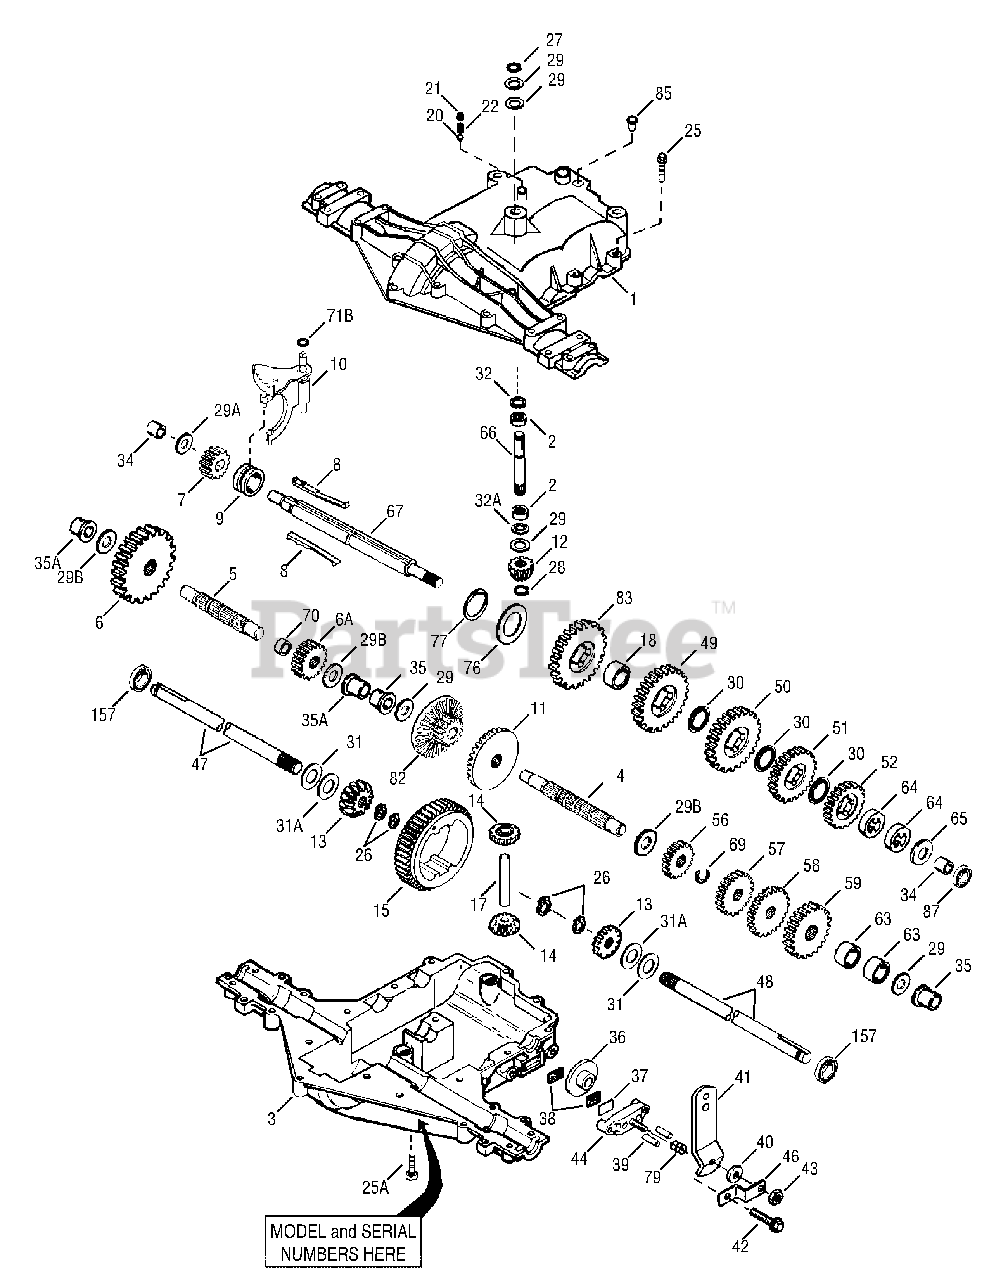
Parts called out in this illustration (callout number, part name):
1	Transaxle Cover
2	Needle Bearing (1/2" long)
3	Transaxle Case
4	Countershaft
5	Output Shaft
6	Spur Gear (38T-PM/SER)
6A	Spur Gear (15T-PM/SER)
7	Spur Gear (11T-PM/SER)
8	Shift Key Set (Qty. 2)
9	Shift Collar
10	Shift Rod & Fork Assembly
11	Bevel Gear (30T-PM)
12	Input Bevel Pinion (13T-PM)
13	Bevel Gear 13T (Incl. ref. 13 & 14)
14	Bevel Gear 13T (Incl. ref. 13 & 14)
15	Ring Gear (43T)
17	Drive Pin
18	Spacer (1.130" x .695")
20	Ball (Stainless Steel 5/16" dia.)
21	Screw, 3/8-16 x 3/8"
22	Spring
25	Screw, 1/4-20 x 1-1/4"
25A	Screw, 1/4-20 x 1-3/8"
26	Retaining Ring-package of 2
27	Retaining Ring
28	Retaining Ring
29	Washer .627" ID .031"
29A	Thrust Washer (.563" ID x .031")
29B	Thrust Washer (.762" ID X .031")
30	Shift Washer (Cupped)
31	Washer .750" ID .56"
31A	Washer .750" ID .062
32	Oil Seal 5/8"
32A	O Ring (.823" OD)
34	Bushing (.563")
35	Flanged Bushing (.625" ID)
35A	Flanged Bushing (.751" ID)
36	Brake Disk
37	Brake Pad Plate
38	Brake Pad (pkg. of 2)
39	Dowel Pin .3125" x .750"
40	Washer .312" ID .059"
41	Brake Lever
42	Screw 1/4-20 x 1-3/8"
43	Lock Nut 5/16-24
44	Brake Pad Holder
46	Bracket
47	Axle (10.719" long) (Incl. 26)
48	Axle (15.312" long) (Incl. 26)
49	Spur Gear (27T-PM/IC)
50	Spur Gear (22T-PM/IC)
51	Spur Gear (19T-PM/IC)
52	Spur Gear (16T-PM/IC)
56	Spur Gear (13T-PM/SER)
57	Spur Gear (18T-PM/SER)
58	Spur Gear (21T-PM/SER)
59	Spur Gear (24T-PM/SER)
63	Countershaft Spacer 1-1/8" x 3/8’’
64	Brake Shaft Spacer 1-3/8" x 3/8’’
65	Washer .563" ID .062
66	Input Shaft
67	Brake Shaft
69	Retaining Ring (.75" x .042")
70	Spacer (.890")
71B	O-Ring
76	Flat Washer (1.128" ID x .058")
77	Retaining Ring (1.125" x .050")
79	Spring
82	Bevel (30T) & Spur Gear
83	Spur Gear (27T-PM/IC)
85	Oil Fill Plug
87	Oil Seal 9/16" ID
157	Oil Seal 3/4" ID
